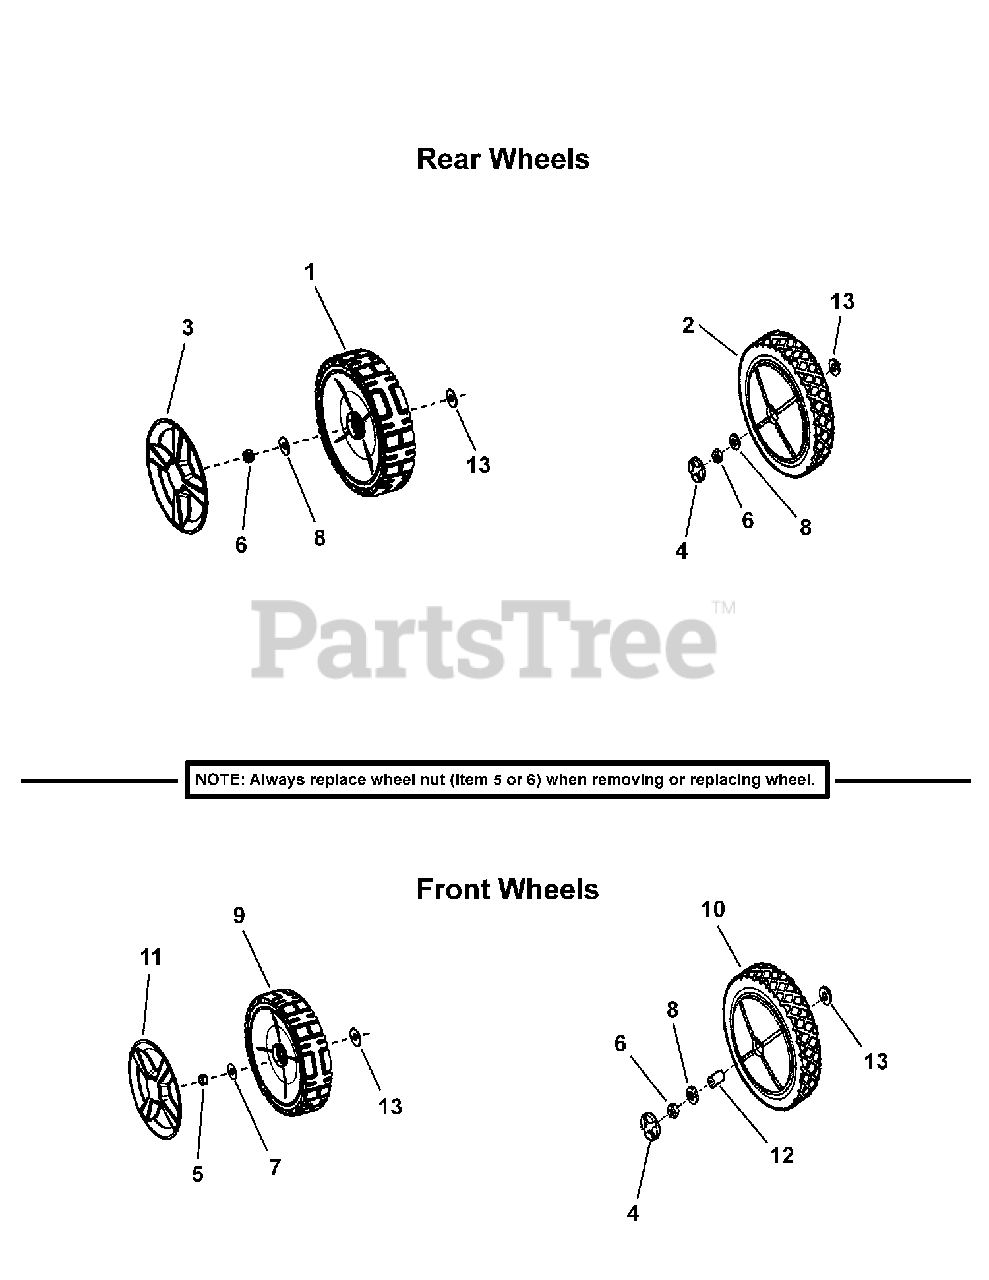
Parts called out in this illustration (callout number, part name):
1	ASSY, Wheel, 10 x 2" Drive w/metal insert Snapper Tread
2	WHEEL, 10 x 1.75" Plastic (self-propelled)
3	HUBCAP, 10" Wheel, Spoked- Snapper Cool Gray
4	PLUG, Wheel
5	NUT, 3/8-16 Hex Center Lock
6	NUT, 7/16-20 Hex Center Lock Jam
7	WASHER, .387 x 1" O.O. Flat
8	WASHER, 7/16" Flat
9	ASSY, Wheel, 8 x 2" Idle, Snapper Tread, Charcoal Gray
10	WHEEL, 8 x 1.75" Plastic
11	HUBCAP, 8" Wheel, Spoked- Snapper Cool Gray
12	BUSHING, Axle
13	WASHER, Shim, .875 x .531 x .060
